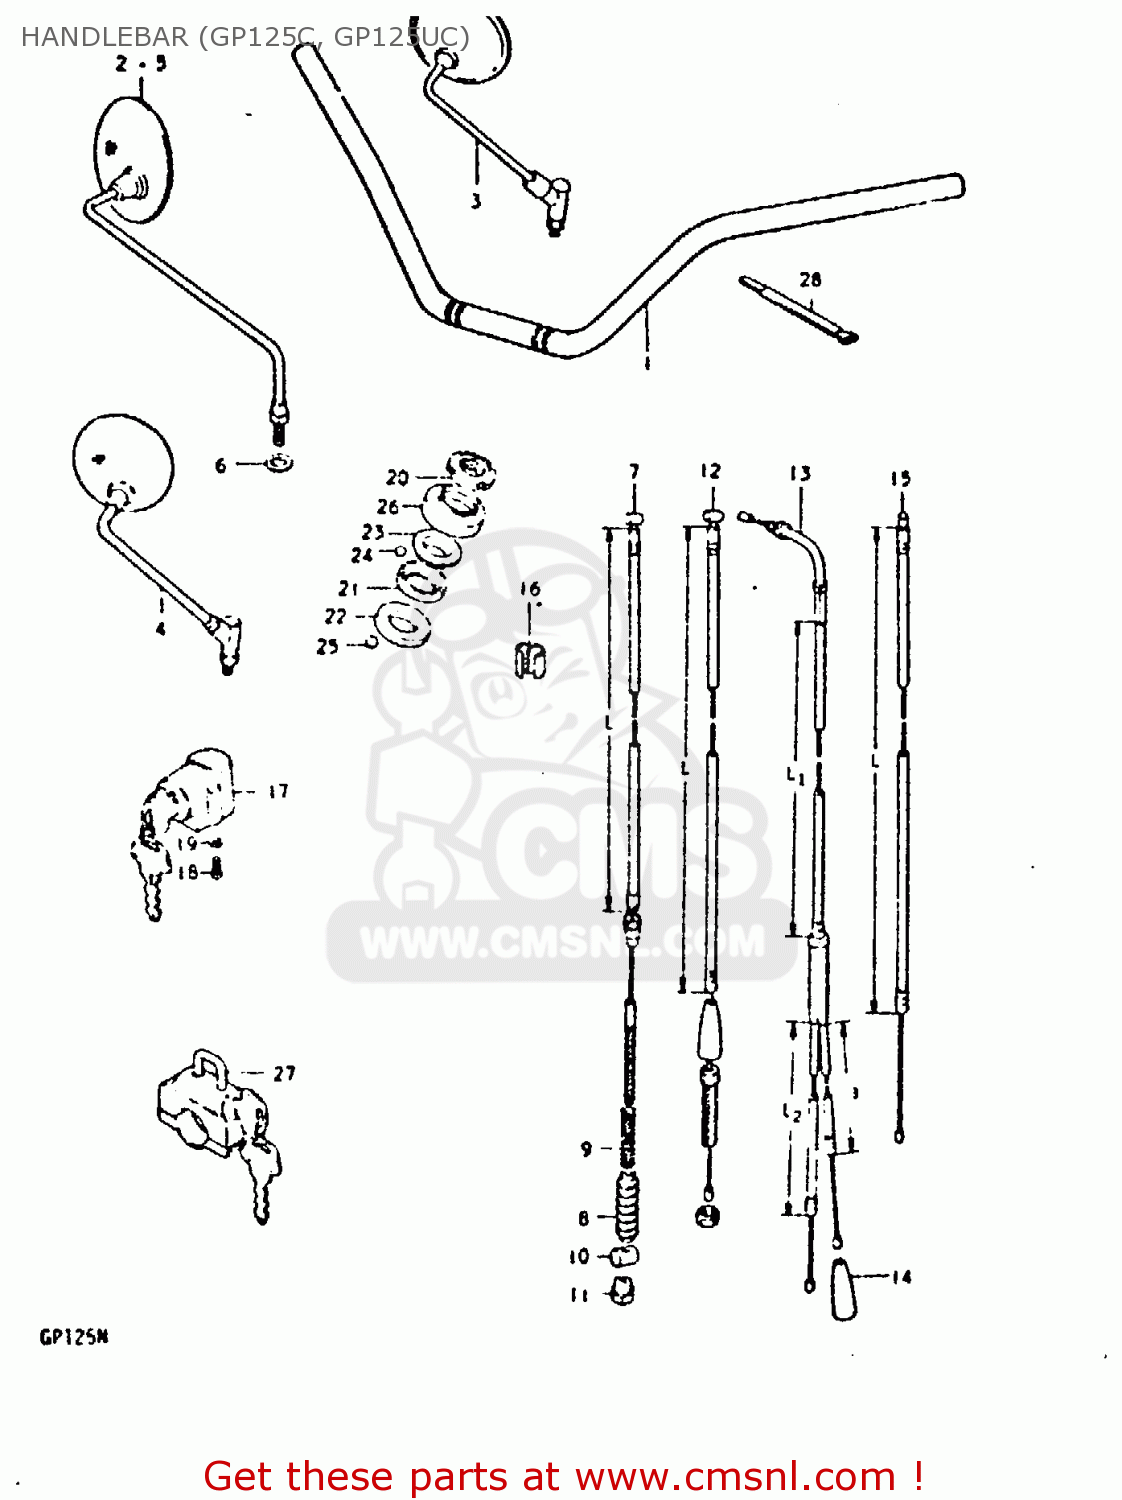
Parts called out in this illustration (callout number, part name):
2	MIRROR ASSEMBLY,RIGHT
3	MIRROR ASSY, REAR VIEW
6	WASHER
7	CABLE ASSEMBLY,FRONT BRAKE
8	SEAL,DUST(7X16X75)
9	SPRING
10	PIN,10X19
11	NUT
12	CABLE ASSY, CLUTCH (L:900)
13	CABLE ASSY, THROTTLE (L1:545, L2:320, L3
14	SEAL,DUST(7X18X30)
15	CABLE STARTER
16	CLIP
17	LOCK ASSEMBLY,STEERING
18	SCREW
19	LOCK WASHER
20	NUT,STEERING STEM(25X44X10)
21	RACE,STEERING INNER UPR
22	LACE,STEERING INNER LWR
23	RACE,STEERING OUTER UPR
24	BALL
25	BALL
26	DUST SEAL,STEERING UPR
28	CLAMP
